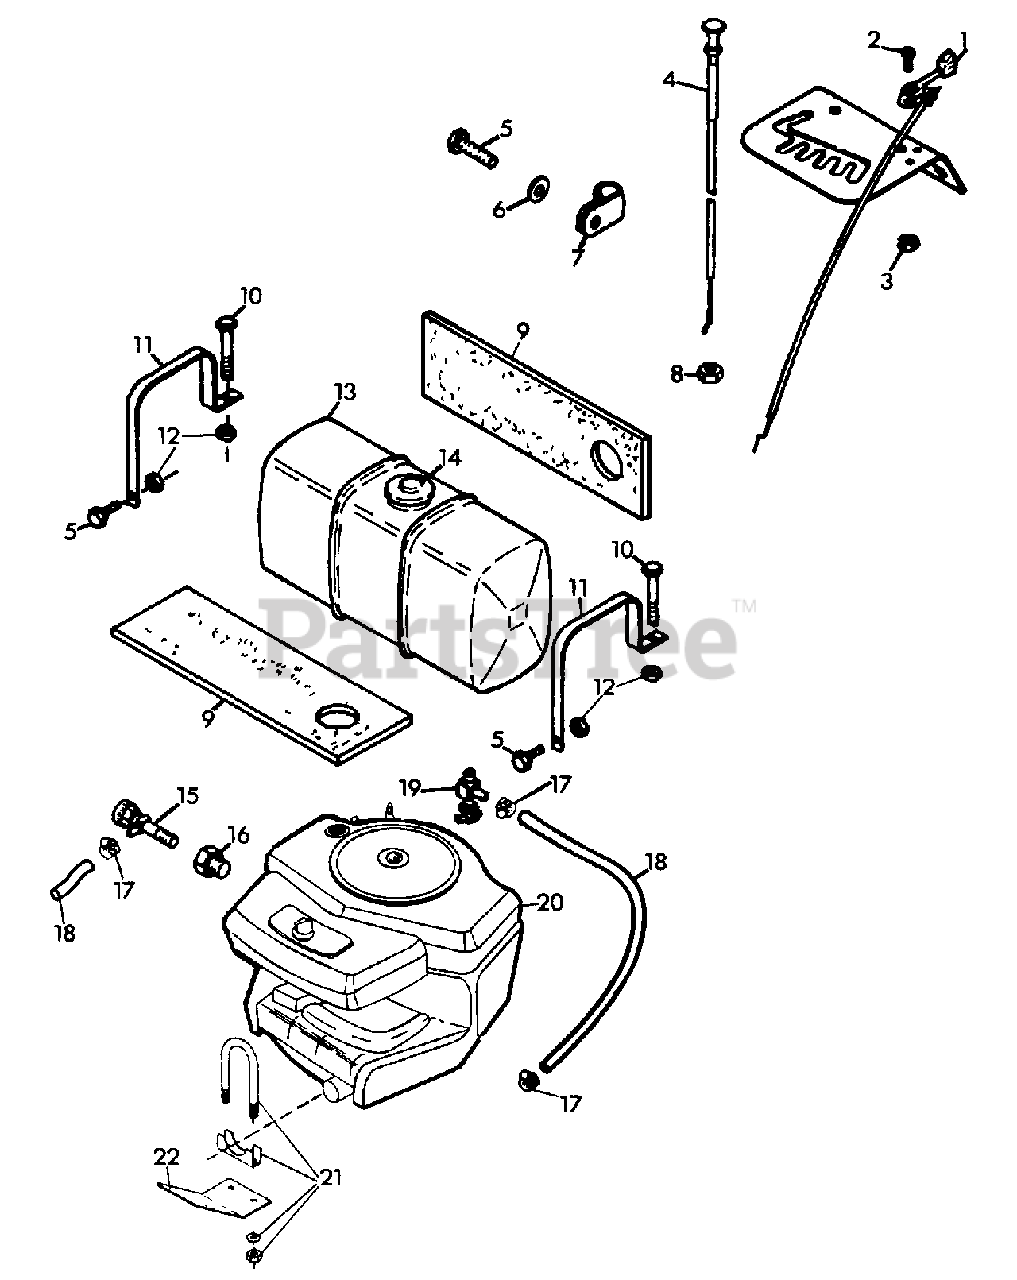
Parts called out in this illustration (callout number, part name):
1	LEVER, CONTROL
2	SCREW, MACH. 10-24X.50 PHD
3	NUT, LOCK 10-24
4	CONTROL, CHOKE
5	BOLT, HEX 1/4-20X.625
6	WASHER, FLAT .281X.625X.065
7	CLAMP
8	NUT, JAM 3/8-24 HEX
9	PAD, GAS TANK
10	BOLT, HEX 1/4-20X1.75
11	STRAP, FUEL TANK
12	NUT, LOCK 1/4-20
13	TANK, FUEL (12 QTS.)
14	CAP, GAS TANK
15	COCK, OIL DRAIN
16	ADAPTOR, OIL DRAIN
17	CLAMP, HOSE
18	LINE, FUEL
19	VALVE AND STRAINER
20	ENGINE, 16 HP B&S
21	CLAMP, MUFFLER
22	DEFLECTOR, EXHAUST
